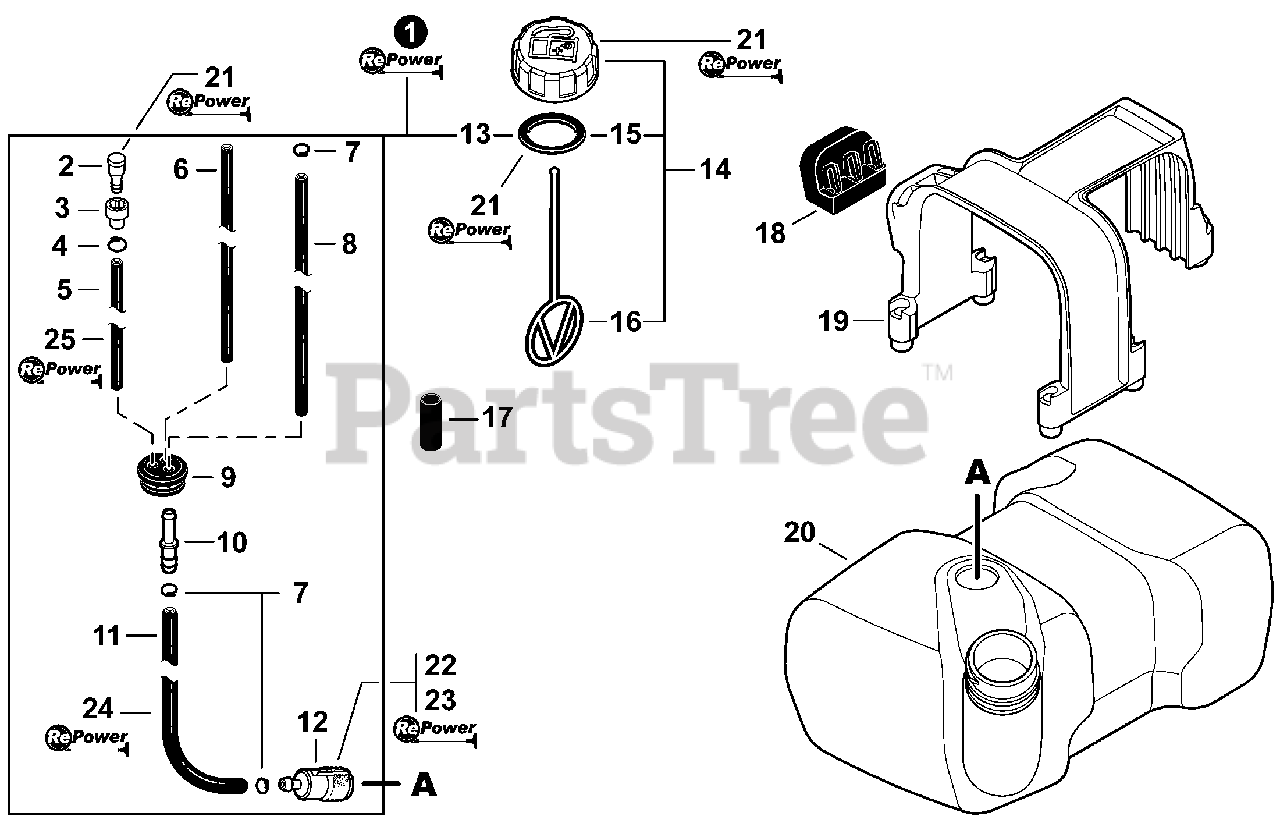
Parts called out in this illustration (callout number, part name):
1	FUEL SYSTEM KIT - REPOWER
2	VENT ASSY
3	HOLDER, VENT
4	CLIP Ø6.5MM
5	PIPE, FUEL VENT 3×6×130
6	PIPE 2.4×5×200 BLACK
7	CLIP Ø6
8	PIPE, FUEL 3×5×135L
9	GROMMET, FUEL
10	CONNECTOR, PIPE Ø5ר3.5
11	PIPE, FUEL 3×5×105L
12	FILTER, FUEL
13	GASKET, FUEL CAP
14	CAP ASSY, FUEL
15	GASKET, FUEL CAP
16	CONNECTOR, CAP L= 100mm
17	TUBE, FUEL LINE 16×18×L40
18	CUSHION
19	RETAINER, FUEL TANK
20	TANK, FUEL
21	CAP/VENT KIT - REPOWER
22	TUNE-UP KIT - REPOWER
23	FILTER KIT - REPOWER
24	PIPE, BULK - REPOWER 3×5mm BLACK
25	PIPE, BULK - REPOWER 3×6mm BLACK
